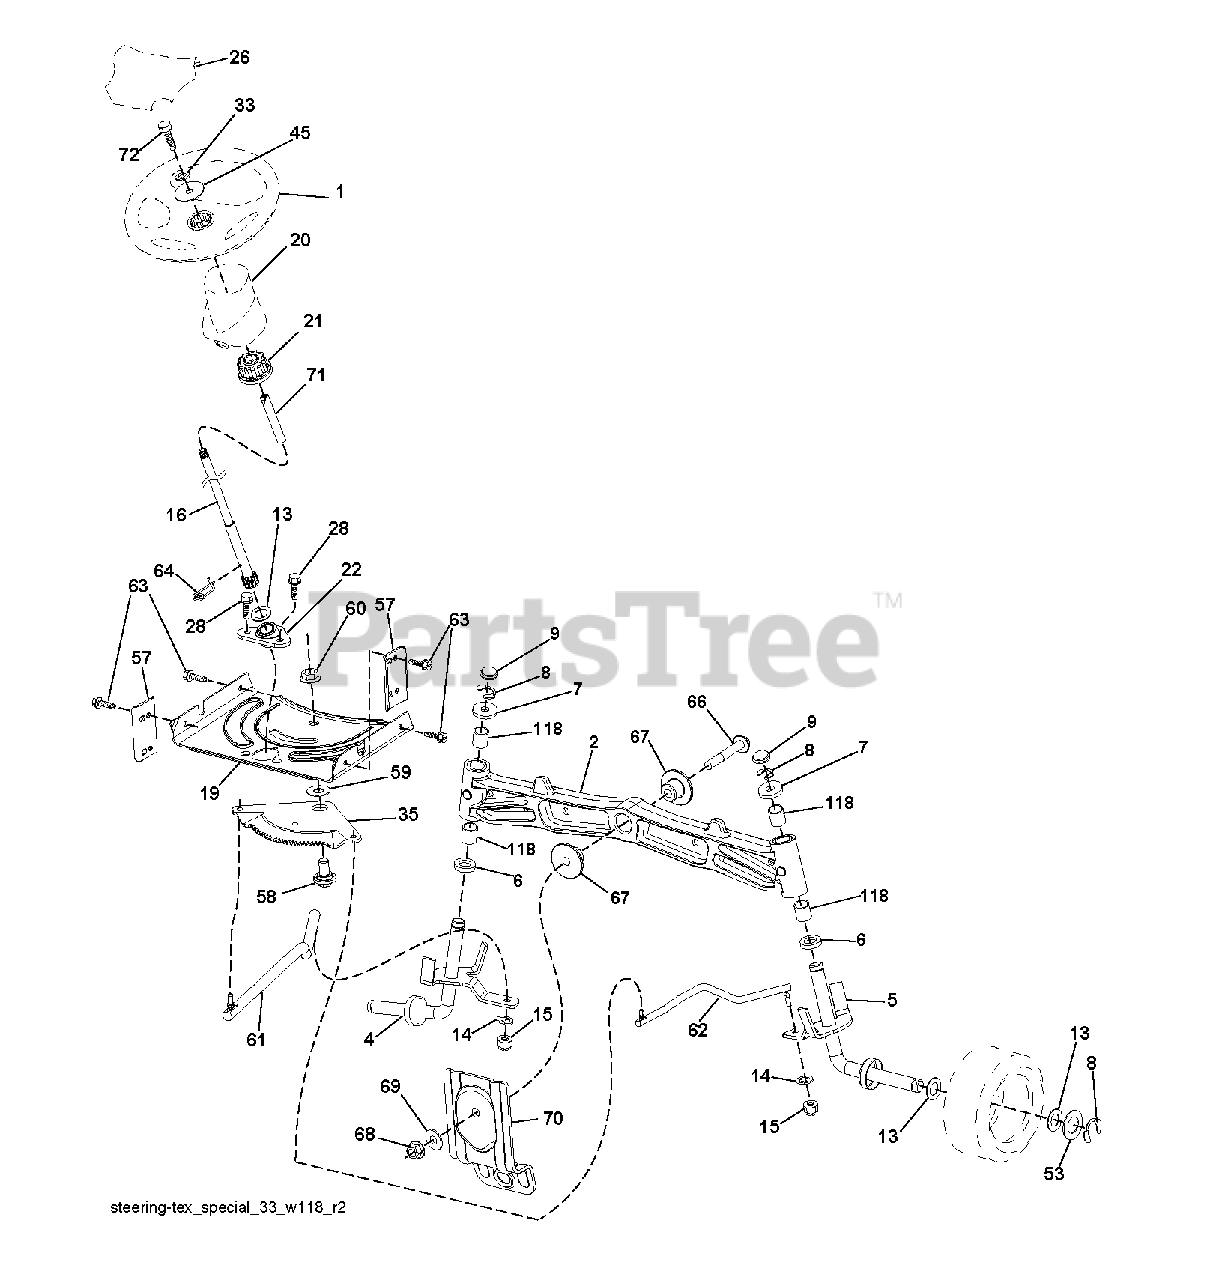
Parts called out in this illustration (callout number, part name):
1	WHEEL, STEERING
4	SPINDLE.WELDED.LH.15"T
5	SPINDLE.WELDED.RH.15"T
6	BRNG T
14	WASHER, LOCK 3/8
15	NUT CROWNLOCK 3/8-24
19	PLATE.STEER.DDL.NLT/NG
21	ADAPTER, WHEEL STNG
22	STEERING.SUPT.LOWER.
26	INSERT, WHEEL STEERING
28	SCREW, 3/8-16X3/4
35	GEAR.SECTOR.PLATE.DDL.
58	BOLT.SHOULDER.SECTOR.P
59	WASHER.THURST.SECTOR.S
60	NUT FLANGE LOCK 5/8-11
61	DRAGLINK.LH.BALLSTUD.D
62	DRAGLINK.RH.BALLSTUD.D
63	SCREW
64	RETAINER.CLIP.SPRING.S
66	BOLT HEX FGHD 7/16-14 X 3 SERR
67	BUSHING.PM.FRONT AXLE
68	NUT.LOCK.FLANGE.7/16
69	WASHER.1.5X.505X.118
70	BRKT.DECK.SUSPENSION.F
